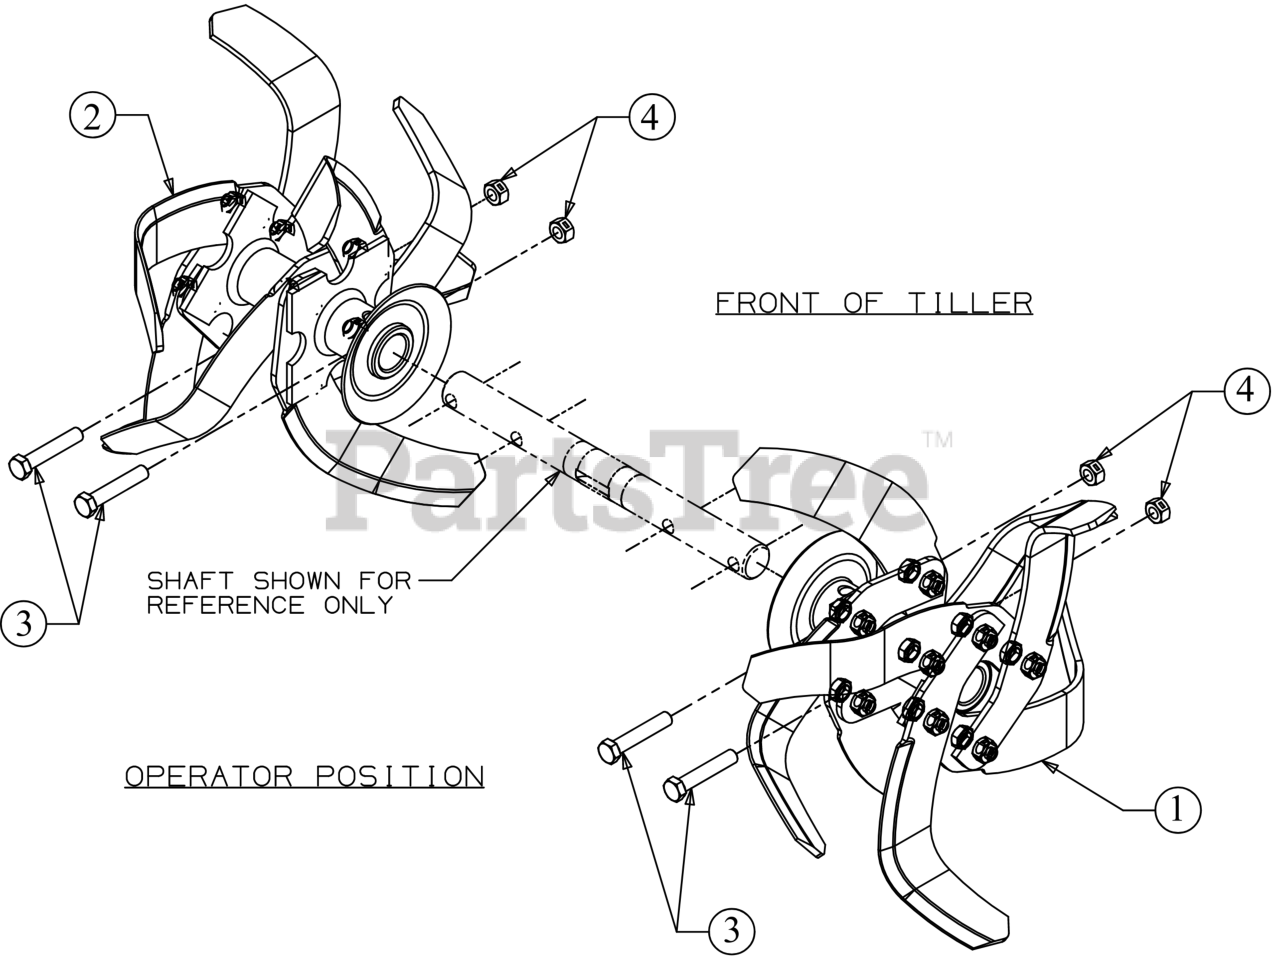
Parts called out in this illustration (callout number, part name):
1	TINE HOLDER ASSEMBLY
1	SCREW 3/8-16 X 1 GR5
1	LOCK NUT 3/8-16
2	TINE HOLDER ASSEMBLY
2	SCREW 3/8-16 X 1 GR5
2	LOCK NUT 3/8-16
3	SCREW 3/8-16 X 2.0 GR 8
4	LOCK NUT 3/8-16
